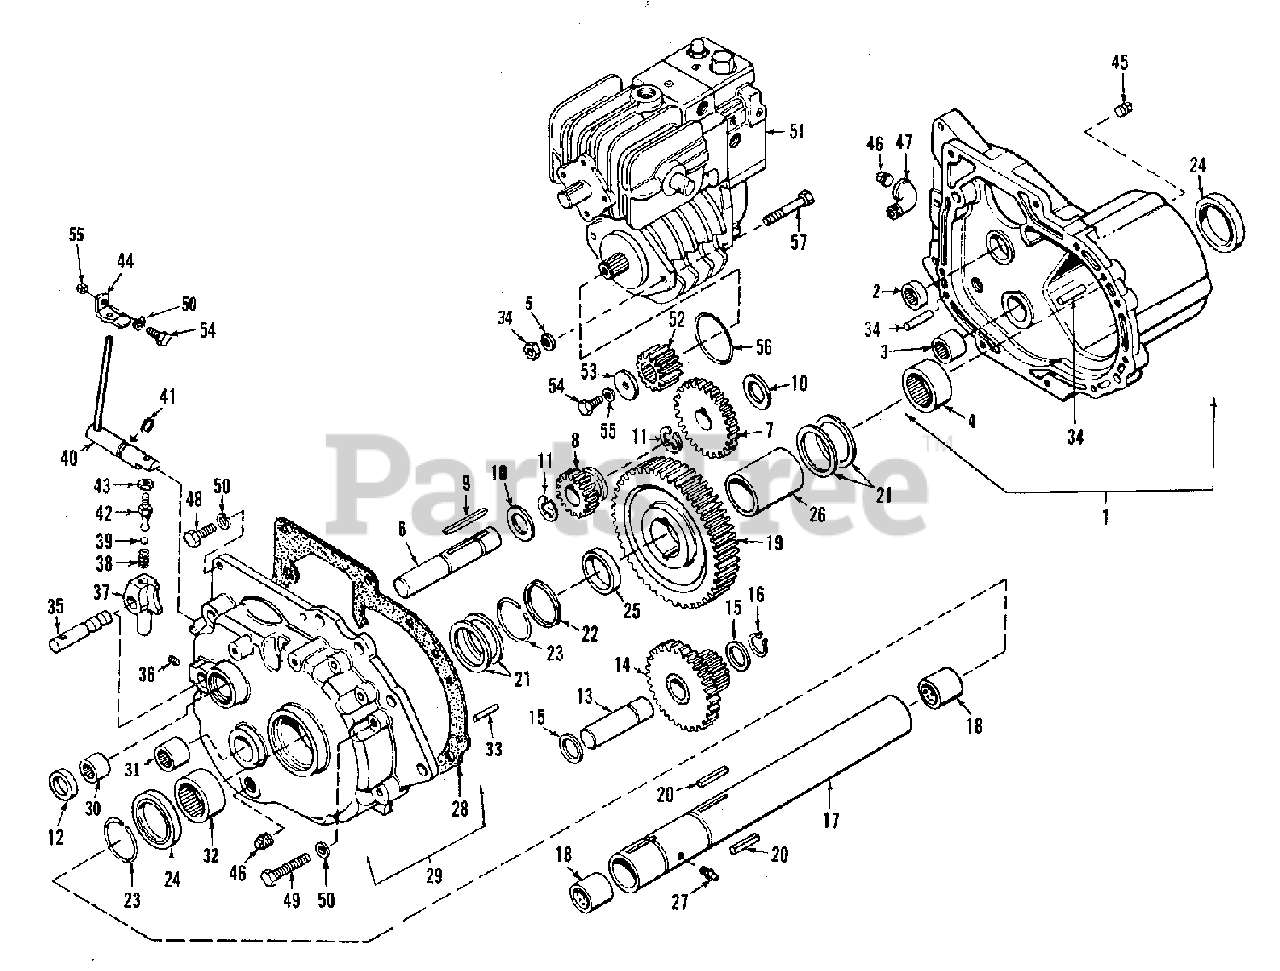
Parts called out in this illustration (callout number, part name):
1	GEAR CASE, Complete
2	BEARING, Needle
3	BEARING, Needle
4	BEARING, Needle
5	WASHER, Lock, 7/16
7	GEAR, 1st Intermediate
8	PINION, Sliding
11	RING, Retainer
13	SHAFT, Intermediate
14	PINION & GEAR ASSEMBLY
16	RING, Retaining
17	AXLE TUBE ASSEMBLY
25	SPACER, Side, R.H.
26	SPACER, Side, L.H.
27	FITTING, Grease
28	GAKSET, Gear Case
29	COVER, Gear Case Sub Assembly
30	BEARING, Needle
31	BEARING, Needle
32	BEARING, Needle
33	PIN, Roll, 3/8 x 1
34	NUT, Full Hex 7/16-14
35	SHAFT, Shifter
36	SCREW, Cone Point, Hollow Head, 5/16-18 x 1/2
39	BALL, Shift Lock
40	SHIFT SHAFT ASSEMBLY
43	NUT, Hex Jam, 5/16-24
44	LATCH, Shift Lever
45	PLUG, Pipe, 1/4
47	ELBOW, Street, 3/8
48	SCREW, Hex Cap, 5/16-18 x 1
49	SCREW, Hex Cap, 5/16-18 x 2
50	WASHER, Lock, 5/16
51	PUMP & MOTOR UNIT, Hydrostatic
52	PINION, Motor Shaft
54	SCREW, Hex Cap, 5/16-24 x 5/8
55	NUT, Hex, 5/16-18
57	SCREW, Hex Cap, 7/16-14 x 4
